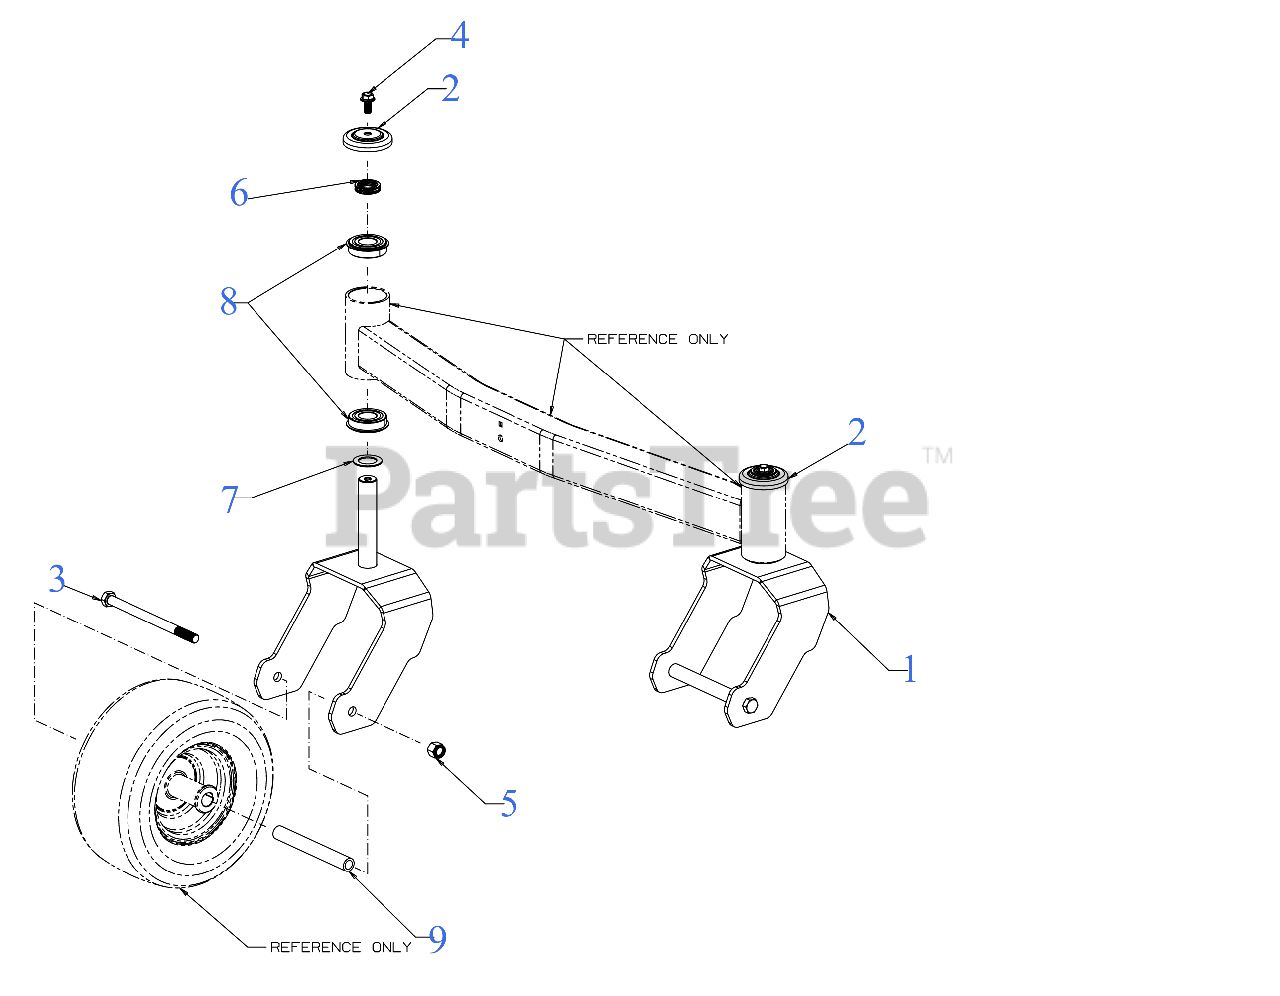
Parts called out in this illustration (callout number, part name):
1	CASTER WHEEL YOKE
3	BOLT 1/2-20 x 7.25 GR5
4	BOLT - 3/8-16:.75:GR5:PATCH LOCK
6	WAVE WASHER
7	WASHER 1.010X1.560X.060
8	BALL BEARING 25X52X15
9	CASTER AXLE SPACER
